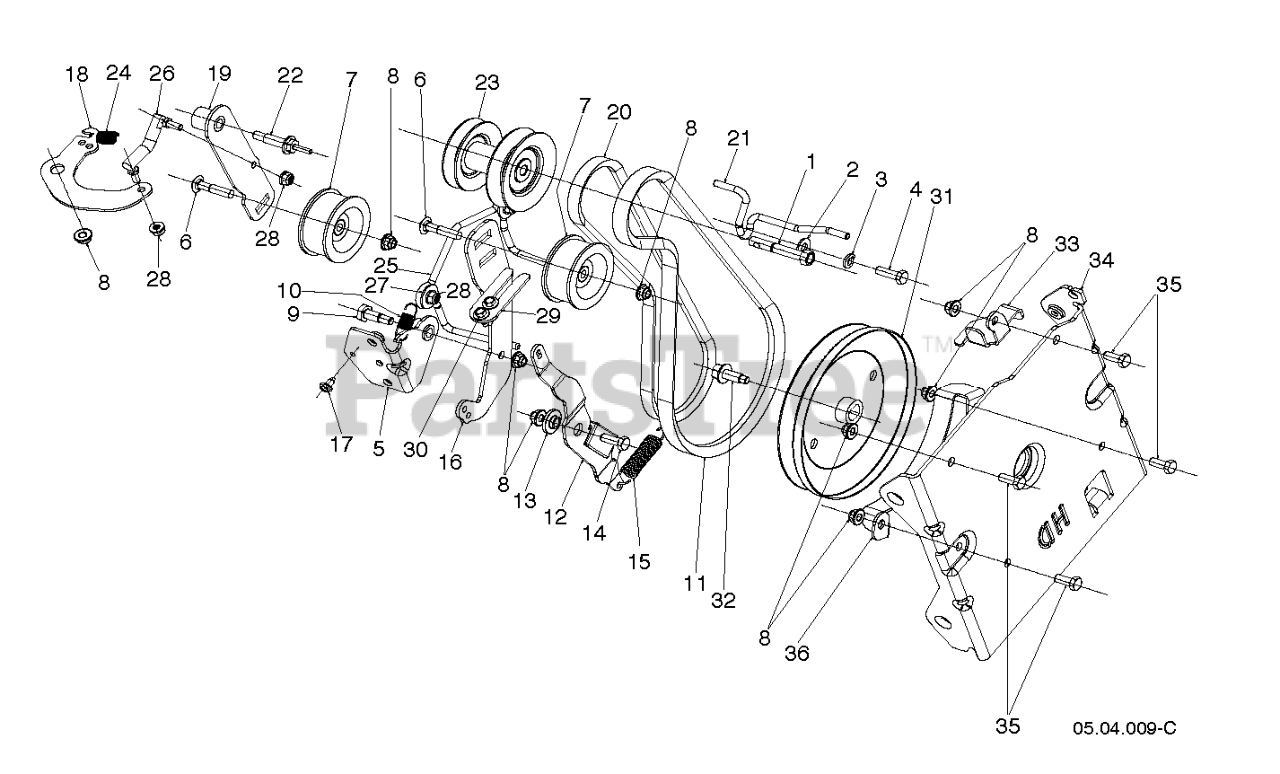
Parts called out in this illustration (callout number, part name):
1	BOLT.ENGINE.PULLEY
2	WASHER 11/32 X 11/16 X 14 GA T
3	WASHER SPRING LOCK WASHER WITH
5	BRACKET WELDMENT, IDLER ARM ZI
6	BOLT 5/16-18 CARRIAGE 1.5L
7	PULLEY IDLER
8	NUTNYLOK.FLRANGE.5/16-18
9	SCREW HEX HEAD SHOULDER
10	SPRING IDLER RETURN
11	BELT 5L 39.15L
12	ARM IMPELLER BRAKE
13	BUSHING.BRAKE.ARM
14	BOLT HEXAGON BOLT 5/16-18 X 7/
15	SPRING EXTENSION - BRAKE
16	ARM IDLER BLACK ZINC
18	Bell Cranks
19	ARM DRIVE IDLER BLACK ZINC PLA
20	BELT 4L DRIVE
21	GUIDE BELT - 4L HYDRO, 5L IMPE
22	GUIDE BELT, SHOULDER SCREW
23	PULLEY WELDMENT
24	SPRING EXTENSION - DRIVE
25	GUIDE BELT - HYDRO 2 WITH FAN
26	LINK ASSY DRIVE IDLER
28	NUT FLG, NYLOCK, 1/4-20 GR G C
30	HEX.WASHER.HEAD 1/4-20 X .65
31	PULLEY IMPELLER DD 5L HD
32	SCREW HEXAGON HEAD FLANGE 3/8-
34	BRACKET AUGER HOUSING INTERFAC
35	SCREW HEXAGON HEAD SCREW 5/16-
36	BRACKET.BELT.KEEPER.LOWER.BLAC
